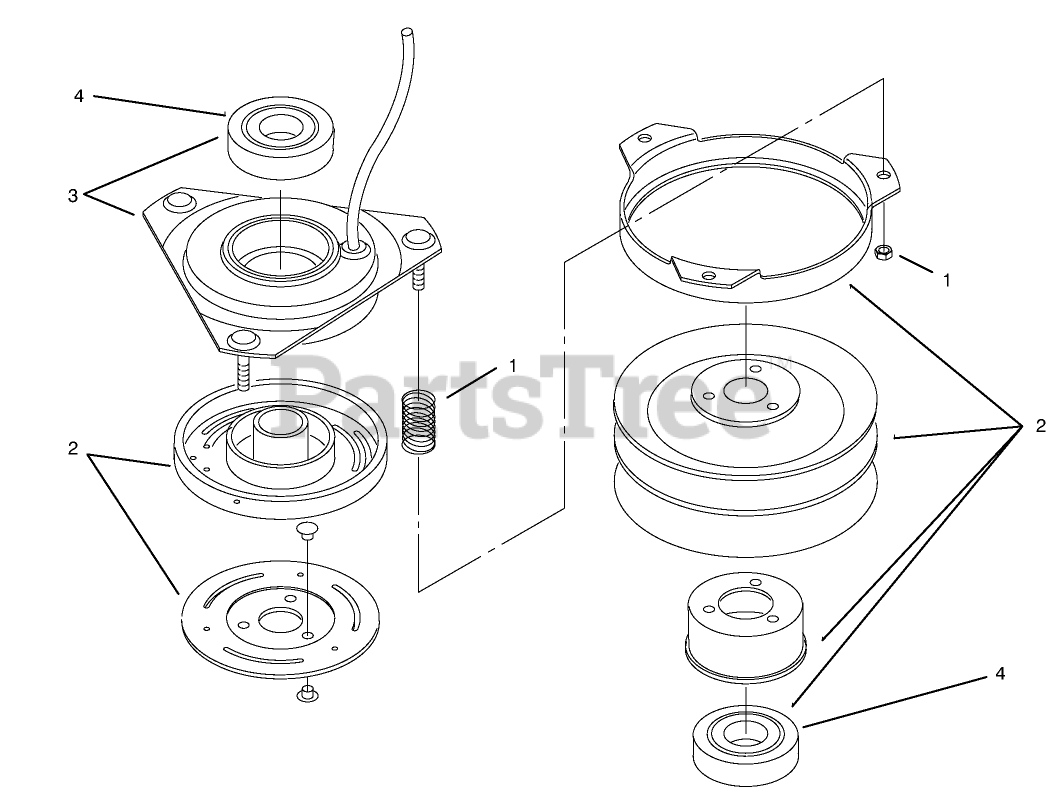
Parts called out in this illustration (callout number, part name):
1	ACCESSORY PKG SRVC PART
2	ROTOR & ARMATURE ASSY
3	FIELD ASSY (SRVC PART)
4	BEARING-ELEC CLUTCH
